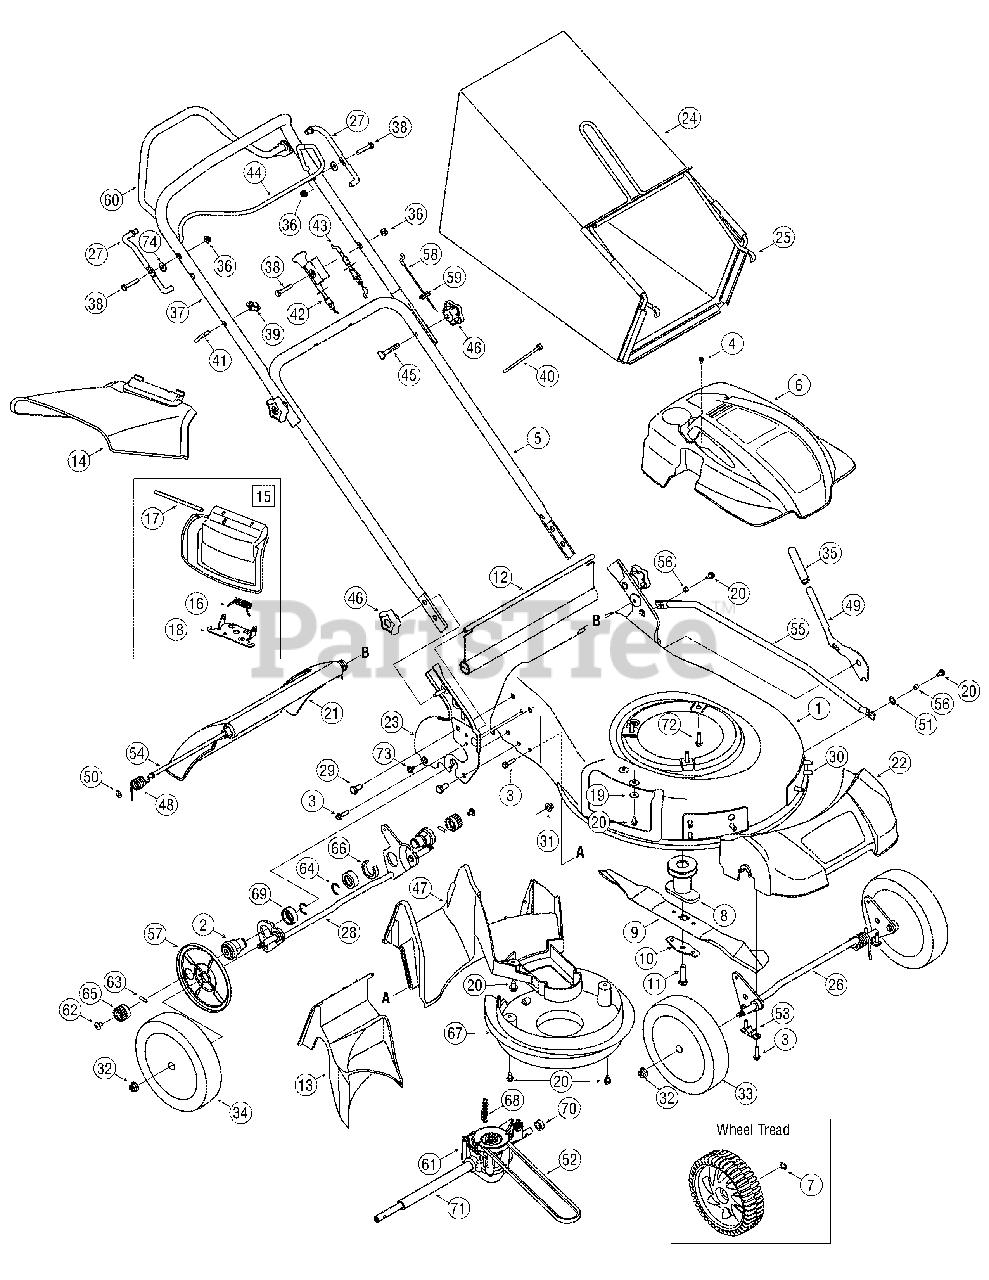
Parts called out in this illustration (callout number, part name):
3	Screw, 1/4-15 x 1.000
4	Screw, Machine, M4-.7 x 10.00
6	Engine Shroud
7	Washer, Wave, .510 x .750 x .017
8	Blade Adapter
9	Mulching Blade
10	Blade Bell Support
11	Screw, 3/8-24 x 1.50
12	Trailing Shield
13	Rear Mulch Plug
14	Side Discharge Chute
15	Mulch Plug (Incl. 16-18)
16	Torsion Spring
17	Hinge Pin
18	Chute Deflector Adapter
19	Beleville Washer
21	Rear Door
22	Front Cover
29	Hhcs, 5/16-18 x .625
30	Screw, 5/16-14 x .750
31	Nut, Flange Lock, 5/16-18
32	Nut, Flange Lock, 3/8-16
33	Front Wheel
34	Rear Wheel
35	Foam Grip
36	Nut, Flange Lock, 1/4-20
40	Cable Tie
41	Rope Guide
42	Choke Cable
43	Control Cable
45	Bolt Carriage, 5/16-18 x 2.0
46	Star Knob
47	Rear Baffle
48	Door Torsion Spring - RH
48	Door Torsion Spring - LH
49	Spring Lever
51	Washer, Wave, .390 x .825 x .016
52	V-Belt
53	Bushing, Lock, .505 Dia. X .62
54	Rear Door Pivot Rod
56	Spacer, 6.60mm ID x 9mm OD
57	Wheel Dust Cover
58	Drive Cable
62	Screw, 1/4-20 x .390
63	Dowel Pin
64	Retainer Ring
65	Spur Gear - RH
65	Spur Gear - LH
66	Spacer, Clip
67	Engine Baffle
68	Extension Spring, .429OD x 2.515
69	Bearing Support Spacer
70	Sleeve Spacer, .550ID x .340 Lg.
71	Sleeve Spacer, .550ID x 7.97 Lg.
72	Screw, 3/8-16 x 1.00
73	Screw, #10-16 x .375
74	Washer, Lock, 1/4
